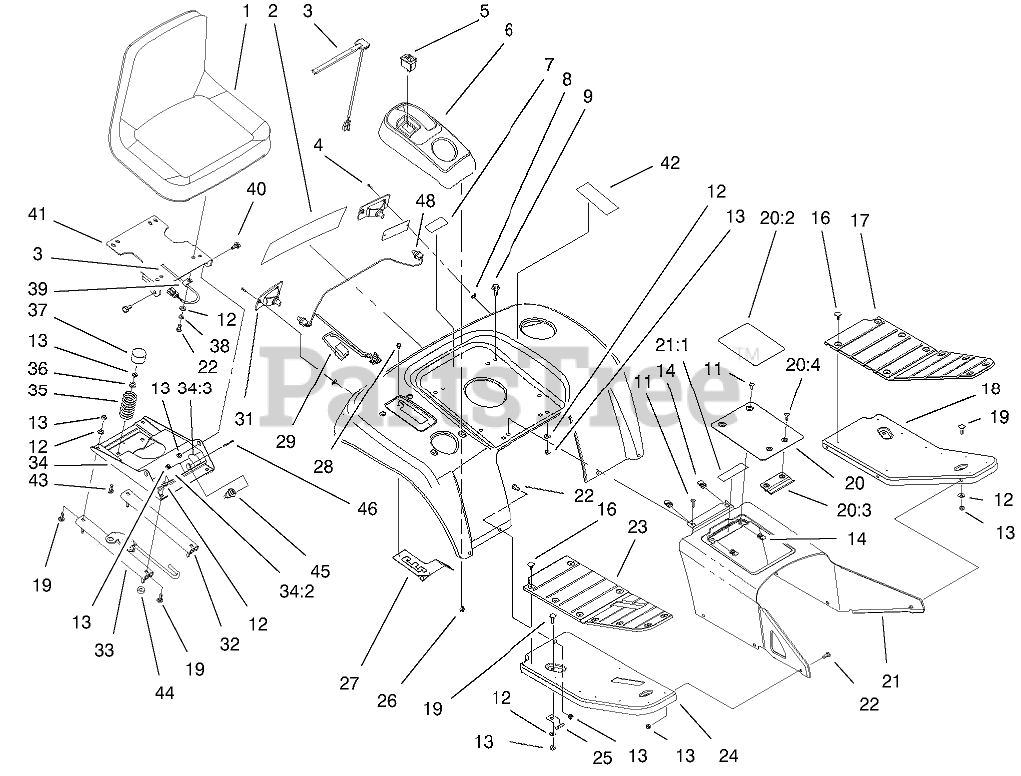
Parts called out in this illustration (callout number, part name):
1	SEAT
2	DECAL - FENDER
3	SWITCH-SEAT
4	SCREW-PPH
5	SWITCH-CRUISE
6	Pod-Control (only on: 73552)
6	Pod-Control Int-l (only on: 73590)
7	Decal-USA (only on: 73552)
8	NUT-SPEED
9	SCREW-HHF
11	SCREW-HH
12	Washer-Flat (only on: 73552)
13	NUT-LOCK, NI
16	FASTENER-PANEL
17	PAD-FOOTREST, LH
18	FOOTREST-LH
19	SCREW-CARR
20	ASM Cover/Decal (only on: 73552)
20	ASM-Tunnel Cover Europe (only on: 73590)
20:2	Decal-Danger (only on: 73552)
20:2	Decal-Danger Europe (only on: 73590)
20:3	RETAINER-COVER
20:4	Screw-PPH (only on: 73590)
21	ASM-Tunnel w/Decal (only on: 73552)
21	ASM-Tunnel w/Decal Europe (only on: 73590)
21:1	Decal-Warning (only on: 73590)
21:1	Decal-Danger (only on: 73552)
22	Screw-HH (only on: 73552)
23	PAD-FOOTREST, RH
24	FOOTREST-RH
25	BRACKET-FOOTREST
26	SCREW-HHFTF
27	GATE-HI / LO SHIFT
28	SCREW-HWH
29	HARNESS-REAR
31	LAMP-TAILLIGHT
32	SLIDE-SLAVE, SEAT
33	SLIDE-LATCH, SEAT
34	Seat Base ASM-Intl (only on: 73590)
34	Seat Base ASM (only on: 73552)
34:2	Decal-Danger (only on: 73552)
34:3	Decal-Nmir Switch (only on: 73552)
35	SPRING-COMPRESSION
36	BUSHING
37	CAP-SPRING, SEAT
38	WASHER-LOCK
39	CLAMP-R
40	BOLT-SHOULDER
41	Mount-Seat
42	DECAL - DIESEL
43	SCREW-CARR
44	WASHER-FLAT
45	STARTER SWITCH ASM
46	KEY-IGNITION
48	LIGHT BULB
